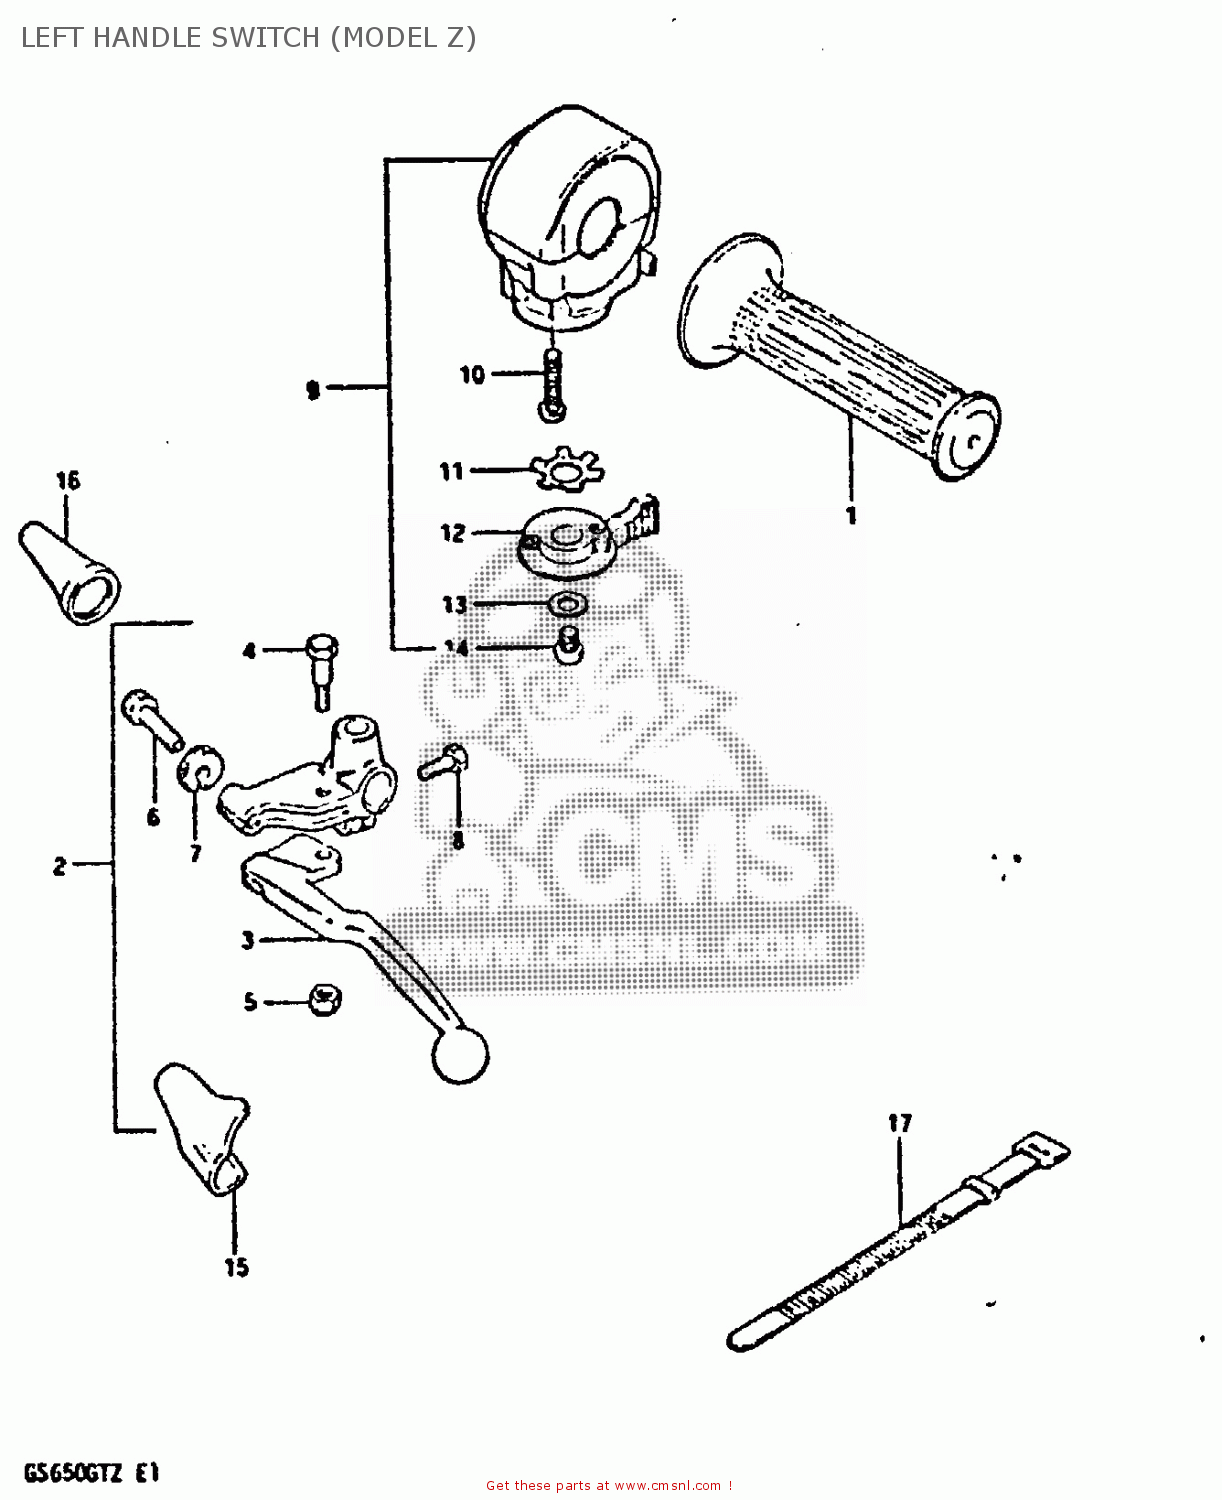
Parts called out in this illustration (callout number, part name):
1	GRIP,LEFT
2	LEVER ASSEMBLY
3	LEVER,CLUTCH
4	BOLT,LEVER
5	NUT 6MM
6	ADJUSTER,CABLE
7	NUT,CABLE ADJUSTER
8	BOLT
9	SWITCH ASSY, HANDLE LH
10	SCREW
11	WASHER
12	LEVER,STARTER
13	WASHER 6MM
14	SCREW
15	COVER,CLUTCH LEVER
16	BOOT,CLUTCH CABLE
17	CLAMP(L:120)
